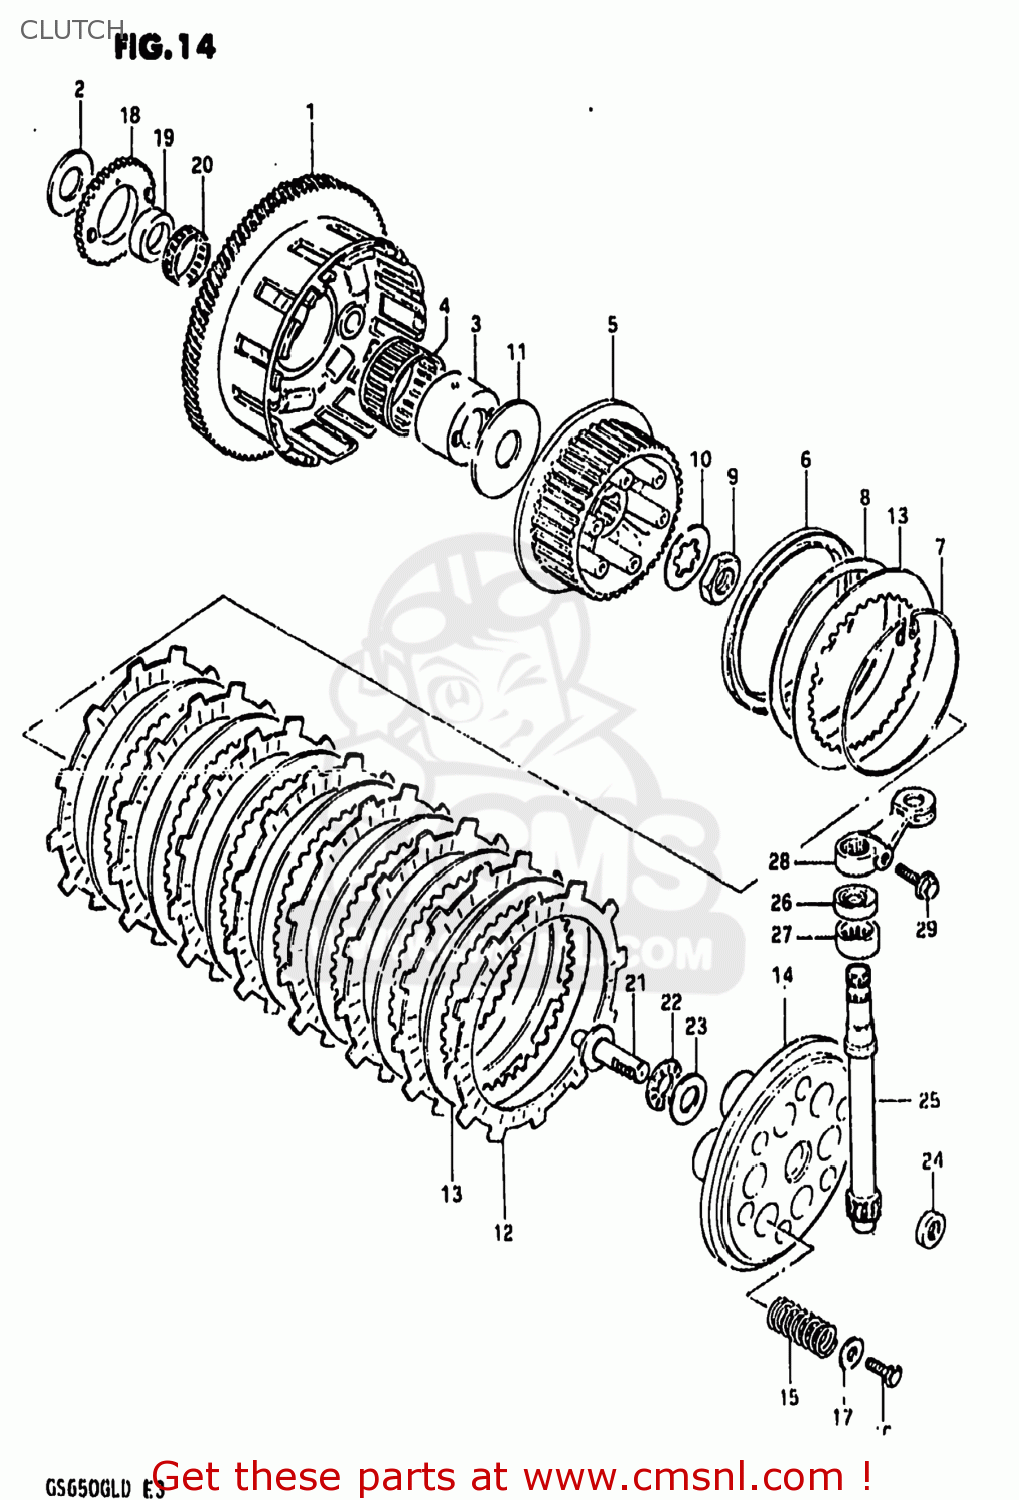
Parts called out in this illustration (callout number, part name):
1	GEAR ASSEMBLY,PRIMARY DRIVE
2	WASHER
3	SPACER
4	BEARING
5	HUB,CLUTCH SLEEVE
6	SEAT,WAVE WASHER
7	RING,STOPPER
8	WASHER
9	NUT
10	WASHER,LOCK
11	WASHER(25X66X3.5)
12	PLATE,CLUTCH DRIVE (MCA)
13	PLATE,CLUTCH DRIVEN(T:2.0) (NAS)
14	DISC,CLUTCH PRESSURE
15	SPRING
16	BOLT, UPPER
17	WASHER
18	GEAR,OIL PUMP DRIVE
19	SPACER,OIL PUMP DRIVE GEAR
20	BEARING(36X40X10)
21	RACK,CLUTCH RELEASE
22	BEARING(15X28X2)
23	WASHER
24	SEAL,OIL(10X16X5)
25	PINION,CLUTCH RELEASE
26	OIL SEAL
27	BEARING(15X22X12)
28	ARM,CLUTCH RELEASE
29	BOLT,REAR
